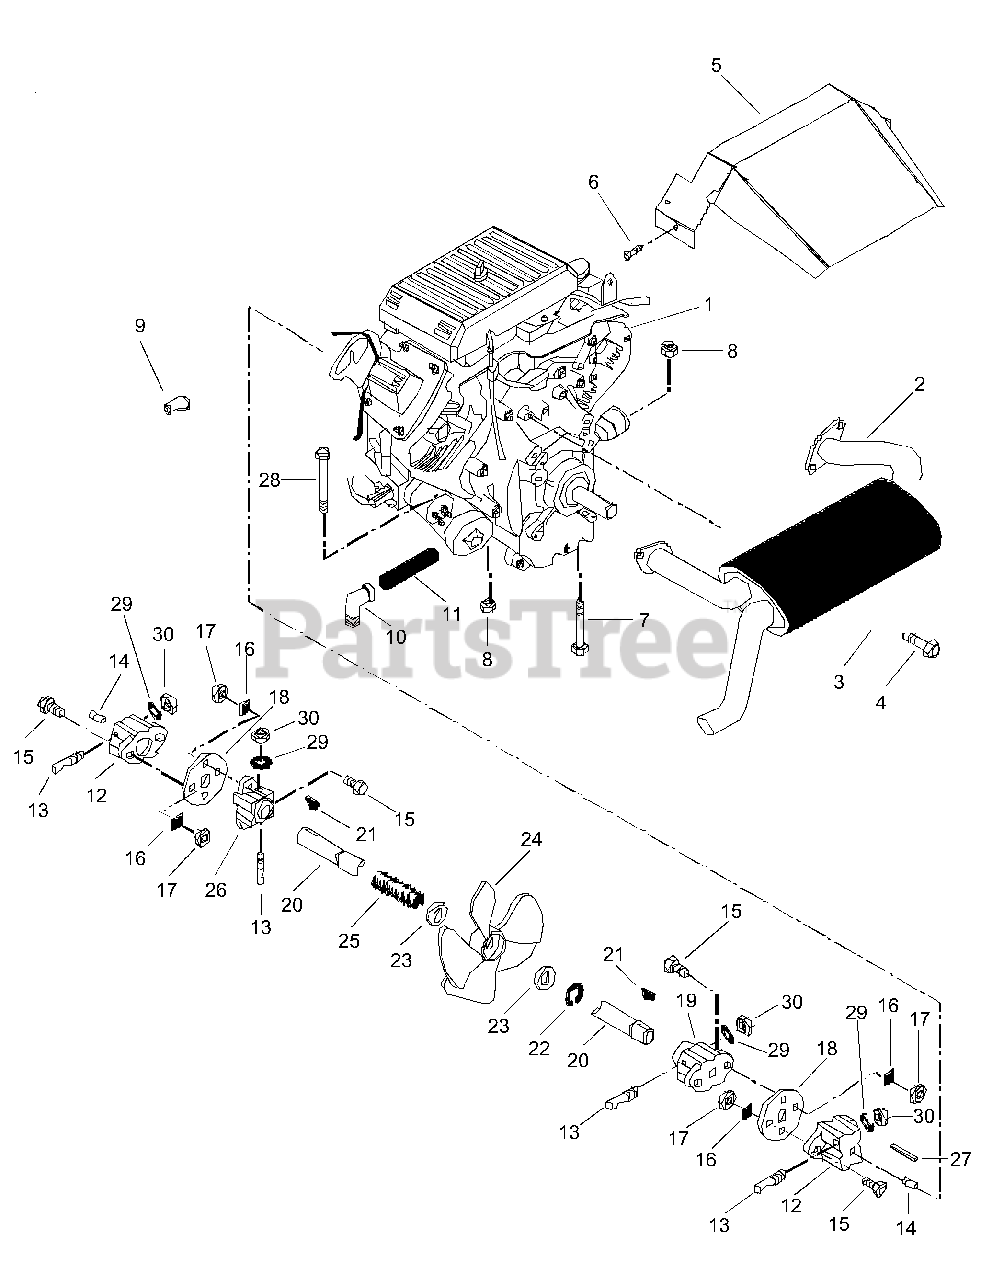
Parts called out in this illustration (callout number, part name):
1	Kohler 22 HP Engine CH22 PS-66540
2	Muffler-Nelson
3	Washer-Locking .438 x .133
4	Bolt-Hex .44-14 x 1.00 Grade 5
5	Heat Shield
6	Bolt-Hex M6 x 1.0 12MM
7	Bolt-Hex .38-16 x 1.75 Grade 5
8	Nut-Locking-Center .38-16
9	Boot-Insulator
10	Elbow .375-18
12	Drive Hub
13	Lock Stud
14	Pin-Groove .313 x .75
15	Bolt-Hex .31-18 x .88 Grade 5
16	Washer-Flat-Steel .344 x .688 x .065
17	Nut-Locking-Center .312-18
18	Spacer Coupling
19	Drive Hub - Twin Shaft
20	Shaft, Drive
21	Key-Woodruff .188 x .75
22	Ring-Retaining-External .750 x .042
23	Washer-Hardened-Thrust .758 x 1.23 x .031
24	Fan
25	Spring-Compression .120 x .75 x 2.50
26	Drive Shaft Hub
27	Key-Square .188 x .75 x .188
28	Bolt-Hex .38-16 x 1.50 Grade 5
29	Washer-Locking .375
30	Nut-Locking .375-16
